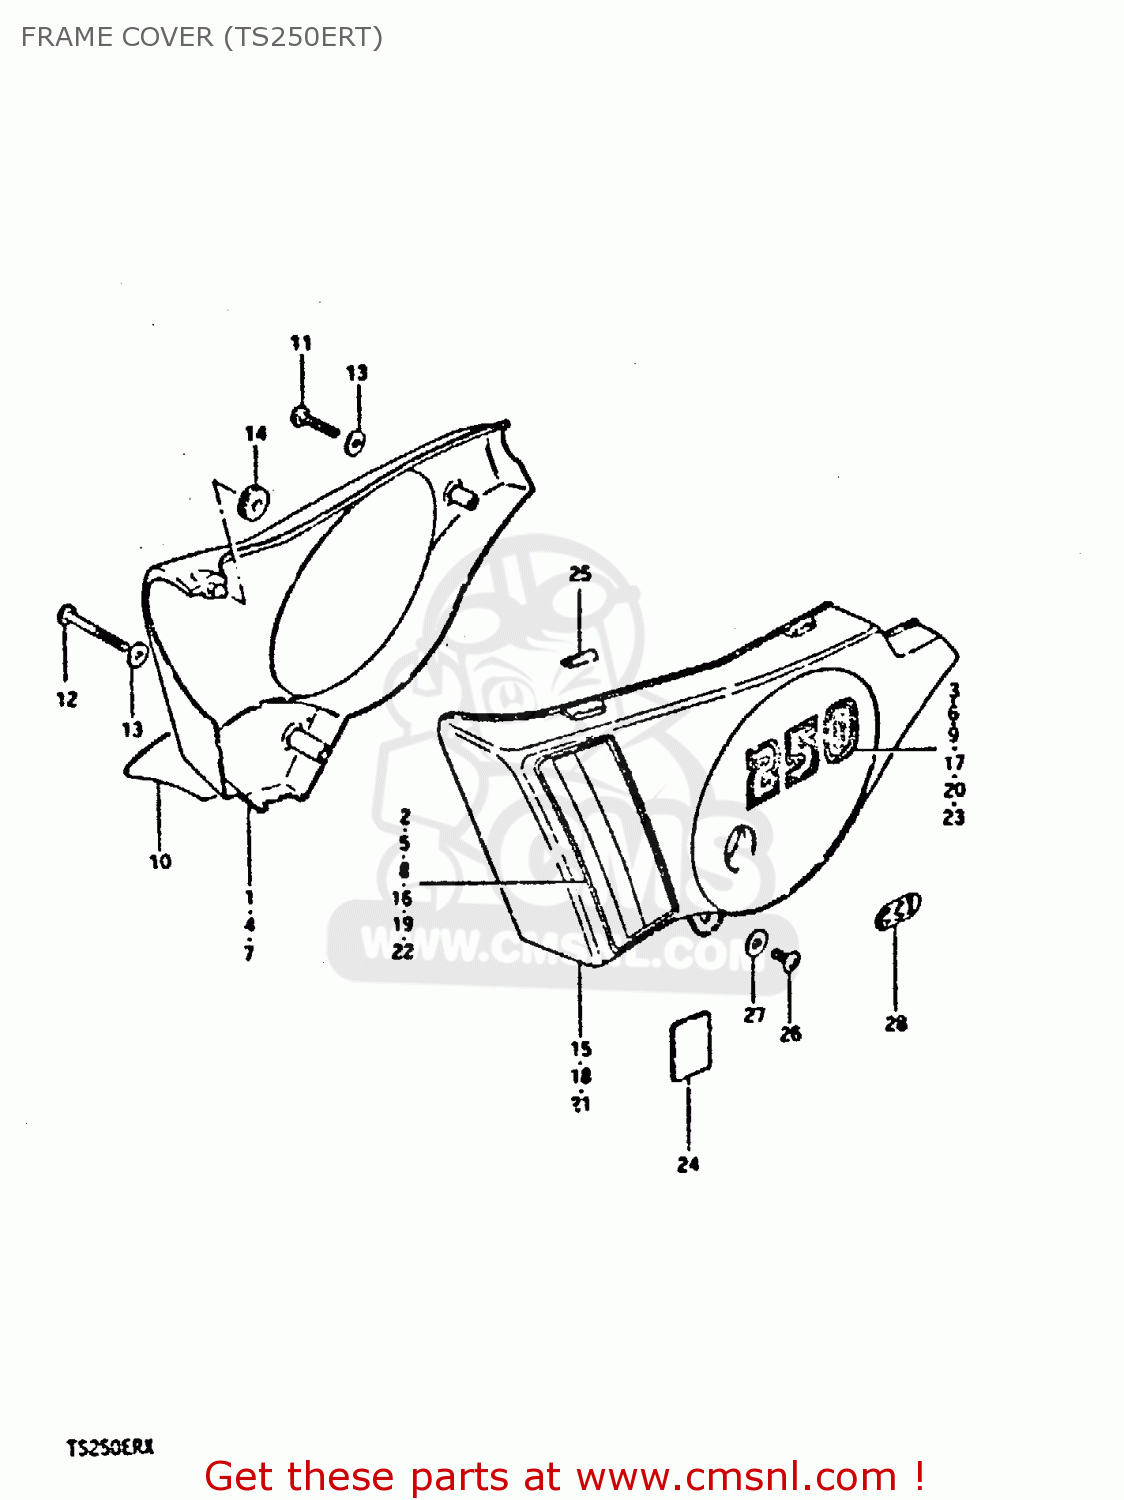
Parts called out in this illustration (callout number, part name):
1	COVER, FRAME RH (RED)
2	TAPE, RH
3	EMBLEM
4	COVER, FRAME RH (YELLOW)
5	TAPE, RH
6	EMBLEM
7	COVER, FRAME RH (WHITE)
8	TAPE, RH
9	EMBLEM
10	EMBLEM,FRAME COVER,RIGHT
11	SCREW
12	SCREW
13	WASHER
14	CUSHION
15	COVER, FRAME LH (RED)
16	TAPE, LH
17	EMBLEM
18	COVER, FRAME LH (YELLOW)
19	TAPE, LH
20	EMBLEM
21	COVER, FRAME LH
22	TAPE, LH
23	EMBLEM
24	PROTECTOR(170X95X3.0)
25	CUSHION,FRAME COVER
26	SCREW 6X12
27	WASHER
28	EMBLEM,CCIS
